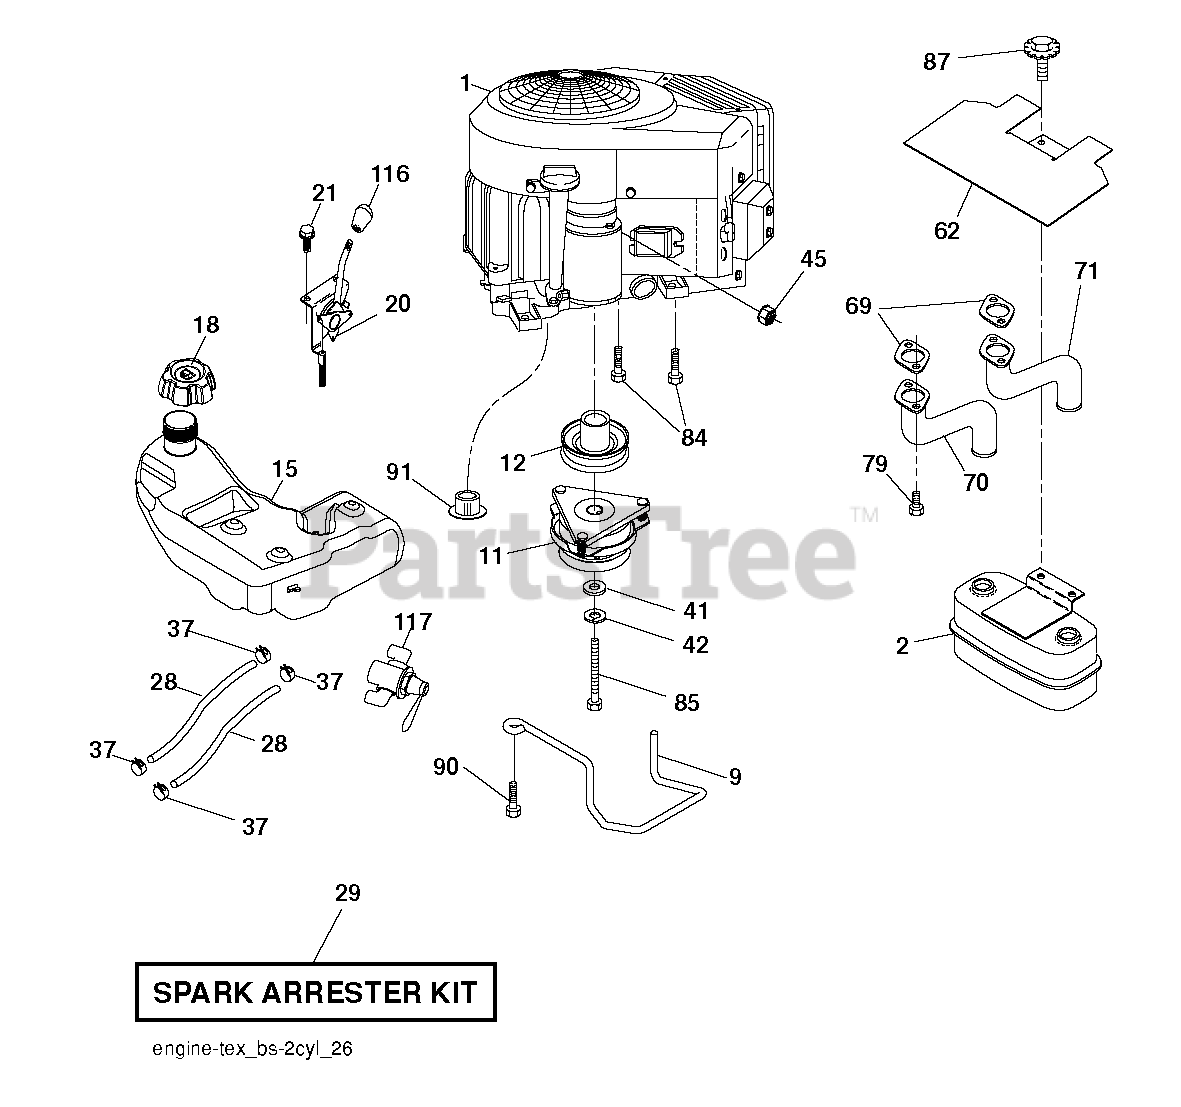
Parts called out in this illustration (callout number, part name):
2	MUFFLER.ASM.TWN.EXTNDED.DFLCTR
9	KEEPER.BELT.ENGINE.4.2
11	CLUTCH MZ ZTR GT.48/54"1.125"
12	PULLEY ENGINE
15	RP_TANK.ASSY.4.GAL.2.PORT.EPA
18	CAP.ASM.FL.RITCH.3"E10.SYM.498
20	CONTROL.THROTTLE.PRO.
21	SCREW.#10 X 0.750.BOS
28	LINE.FUEL.64"REAR.EMIS
29	KIT.SPARK ARRESTOR 794945 B&S
37	HOSE CLAMP
42	LOCKWASHER
45	NUT
62	SHIELD.HEAT.MUFFLER
69	GASKET.MUFFLER
70	RP.EXHAUST.TUBE.LH.BS/TWIN
71	EXHAUST.TUBE.RH.BS/TWIN
79	SCREW.SOCKET.HEAD.5/16-18
84	SCREW.3/8-16
85	BOLT HEX 7/16-20 X 3.75 GR. 5
87	BOLT.5/16-18UNCX3/4 W/SEMS.BLK
90	SCREW 3/8-16X1
91	BUSHING.1.375OD
116	KNOB - SHIFT
117	VALVE FUEL RESERVE
